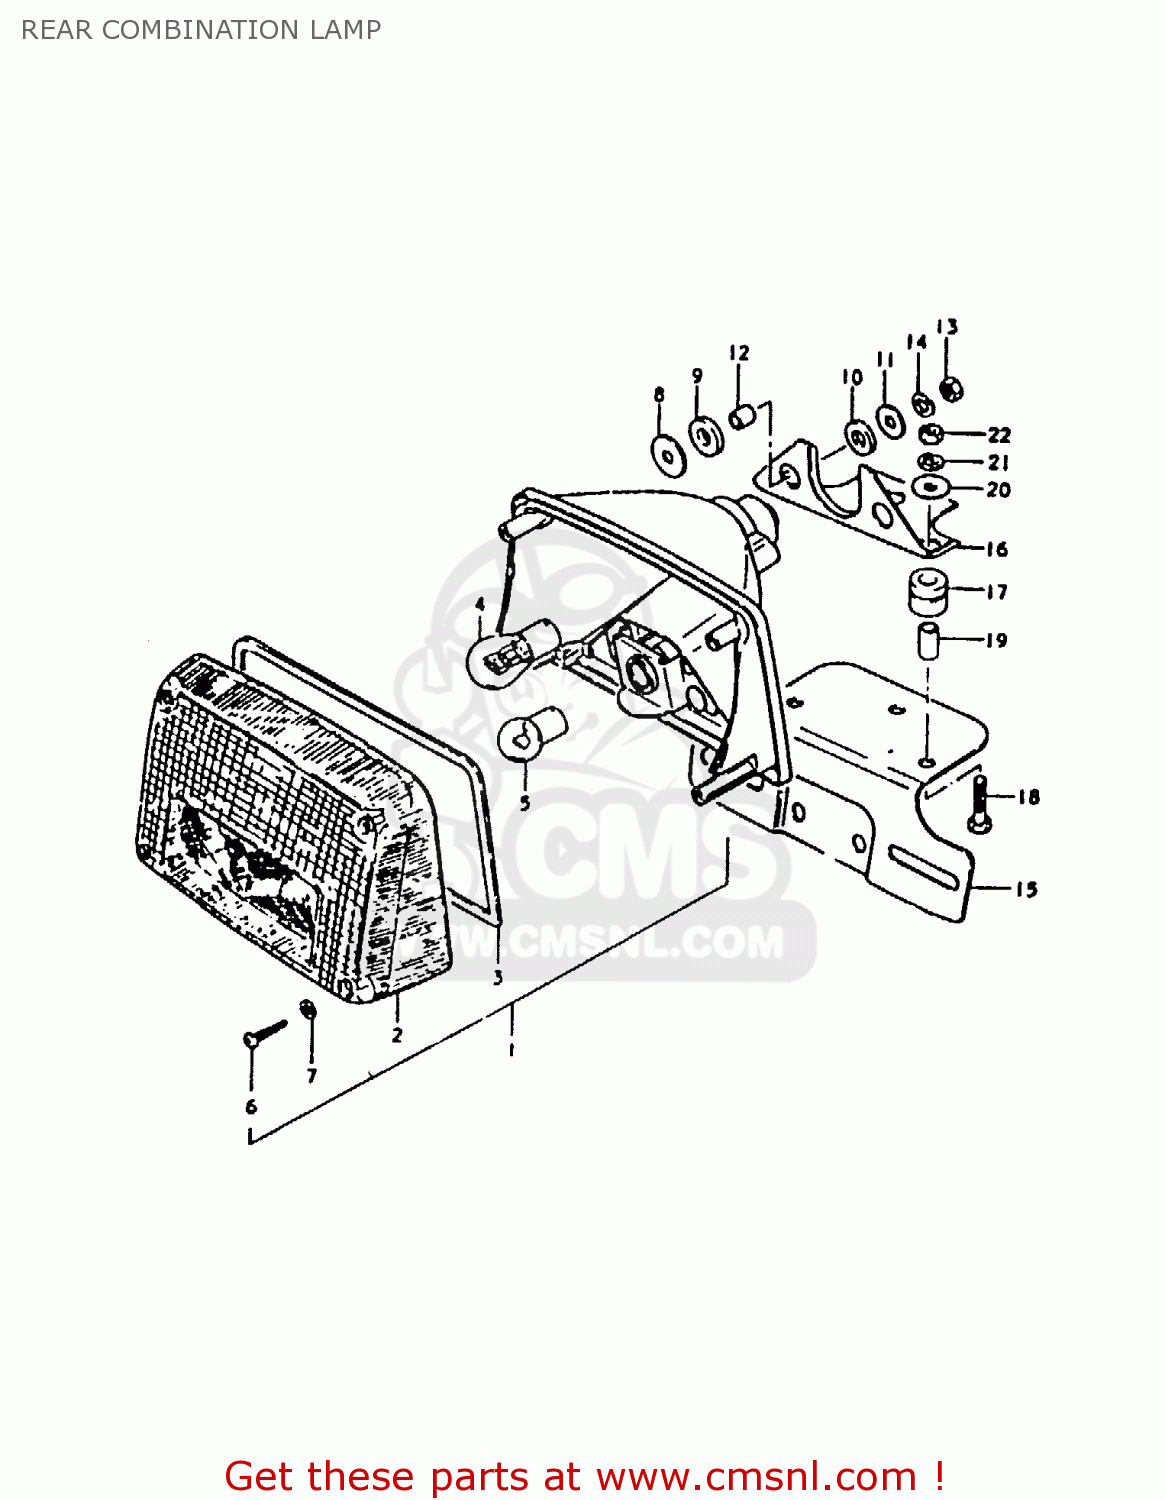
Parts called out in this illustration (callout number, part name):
1	LAMP ASSEMBLY,REAR COMBINATION
2	LENS,REAR COMBINATION LAMP
3	GASKET (NAS)
4	BULB(12V23W)
5	BULB
6	SCREW
7	GASKET (NAS)
8	WASHER
9	CUSHION
10	CUSHION
11	WASHER (6.5X24X1.6)
12	SPACER(6.1X9X7.5)
13	NUT
14	LOCK WASHER
15	PLATE, LICENSE
16	BRACKET,LICENSE PLATE
17	CUSHION, BRACKET
18	BOLT
19	SPACER (6.1X8X15.5)
20	WASHER
21	LOCK WASHER
22	NUT
